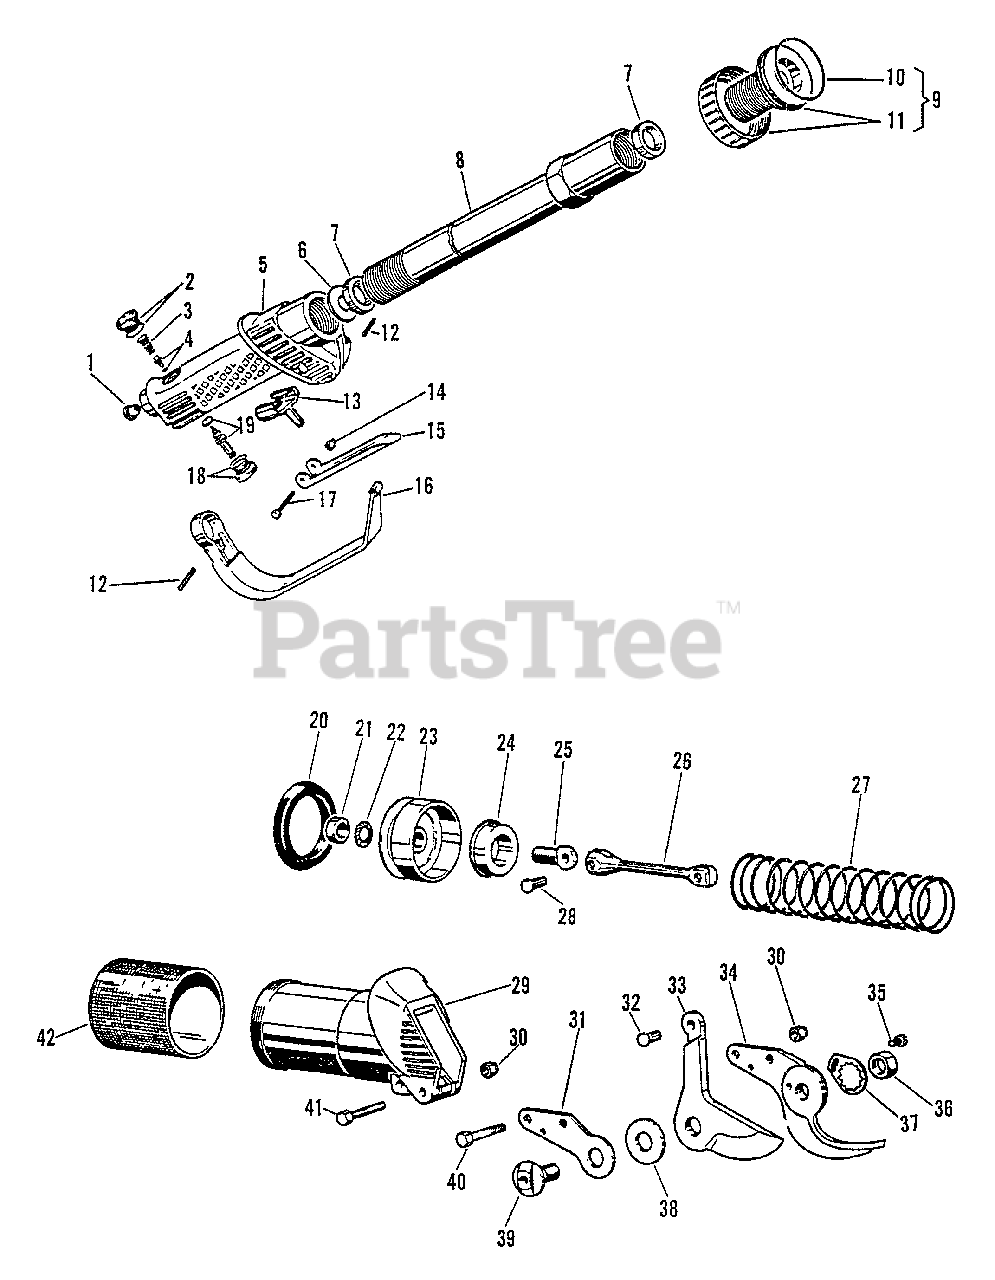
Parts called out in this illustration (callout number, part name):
1	FILTER, AIR
2	FITTING, END W/O-RING
3	SPRING
4	VALVE, PIN W/O-RING
5	BODY, HANDLE
6	SPACER
7	WASHER - RUBBER
8	EXTENSION, AIR 1 FOOT
9	COMPLETE ADAPTER FOR SE-2
10	O-RING
11	ADAPTER FOR SE-2
12	PIN, ROLLER
13	SAFETY
14	NUT
15	TRIGGER, THROTTLE
16	GUARD, HANDLE
17	PIN, TRIGGER
19	VALVE W/O-RING
20	RING, PISTON
21	NUT
22	LOCKWASHER
23	PISTON
24	STOPPER
25	PISTON, LINK
26	ROD
27	SPRING
28	RIVET
29	BODY, CYLINDER
30	LOCKNUT
31	SUPPORT, BLADE
32	RIVET
33	BLADE, BASIC
34	ANVIL, BASIC
35	SCREW, SET
36	LOCKNUT
37	HOLDER, NUT
38	SPACER, BLADE
39	BOLT
40	BOLT
41	BOLT
42	GRIP, HANDLE
7001330111	CAP
